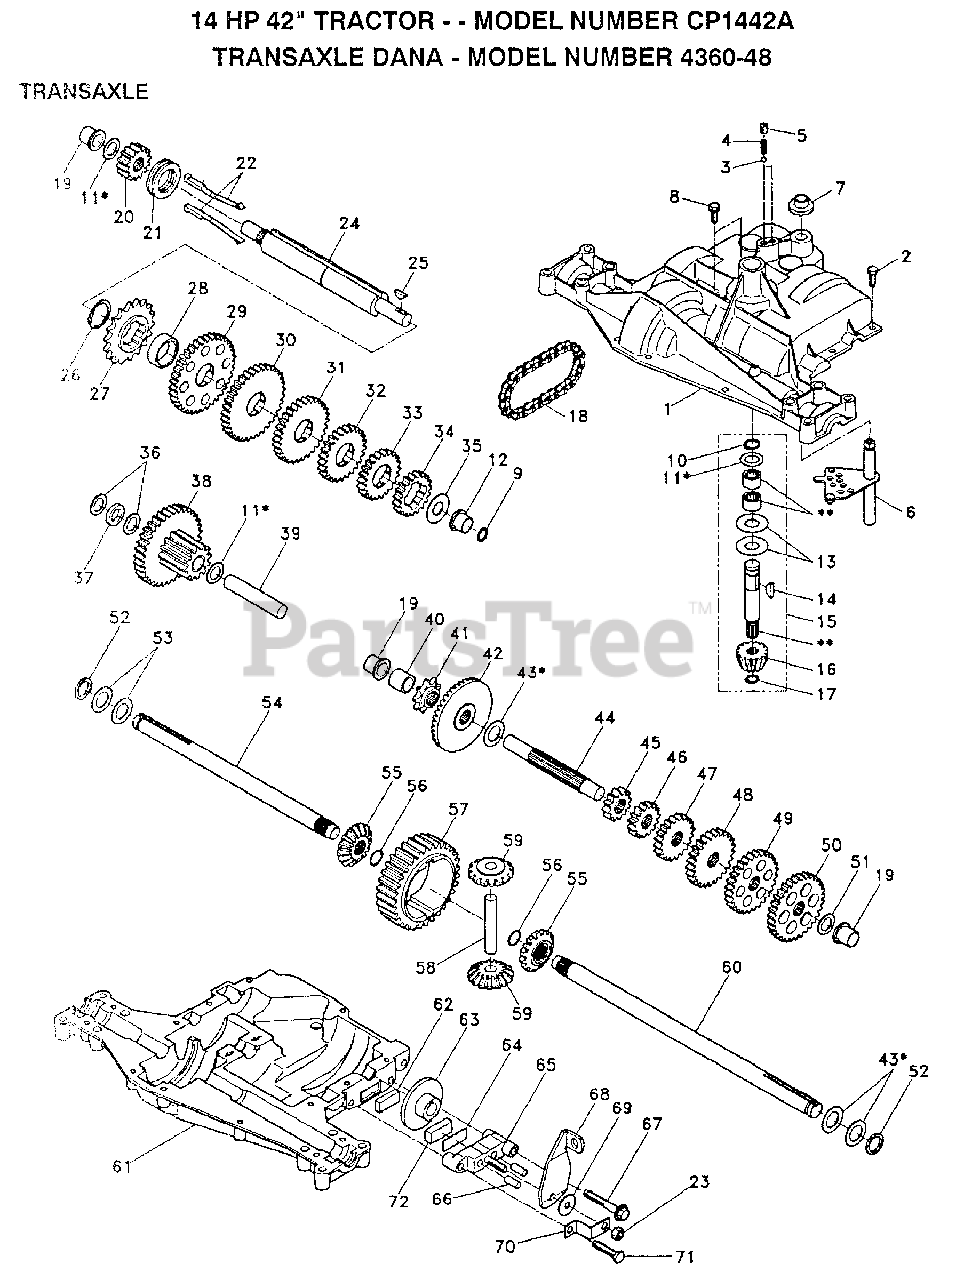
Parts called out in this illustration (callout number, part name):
4	"SPRING, DETENT LT"
5	"SCREW, SET LT"
6	KIT SHIFTER ASM
7	SHIFTER BOOT
8	SCREW TAP W/SEAL
9	SQUARE RING
10	RETAINING RING LT
11	ASM KIT SHIM 4689
12	"FLANGE, BEARING"
13	WASHER T
14	WOODRUFF KEY
15	AS KIT INPUT SHFT
16	PINION 14T T
17	"RING,RETAINING LT"
18	"CHAIN,24 PTCH LT"
19	BEARING.FLNG.5510
20	GEAR SPUR 14T
21	COLLAR CLUTCH
22	ASM KIT CLTCH KEY
23	NUT.LOCK.5/16-24
24	SHAFT INTERM
25	WOODRUFF KEY
26	"RING,RETAINING LT"
27	SPROCKET 18T T
28	SPACER YT
29	KIT.GEAR.12/37TH
32	GEAR 25T LT
33	GEAR SPUR 22 TT
34	SPUR GEAR 19T
35	"WASHER, PLAIN LT"
36	WASHER 025
37	SPACER
38	ASSM GEAR COMB
39	SHAFT IDLER
40	SPACER T
41	SPROCKET 9T LT
43	ASM KIT SHIM
44	SHAFT T
48	"GEAR, SPUR 25T LT"
49	GEAR 28T T
50	"GEAR, SPUR 31T LT"
51	WASHER 060
52	NEOPRENE WASHER
53	WASHER 031
55	GEAR 15T T
56	"RING,RETAINING LT"
58	SHAFT T
59	GEAR 1ST T
62	PUCK T
63	BRAKE DISC. T
64	SPACER LT
66	PIN T
69	WASHER LT
71	"SCREW, TAPPING LT"
72	PUCK T
